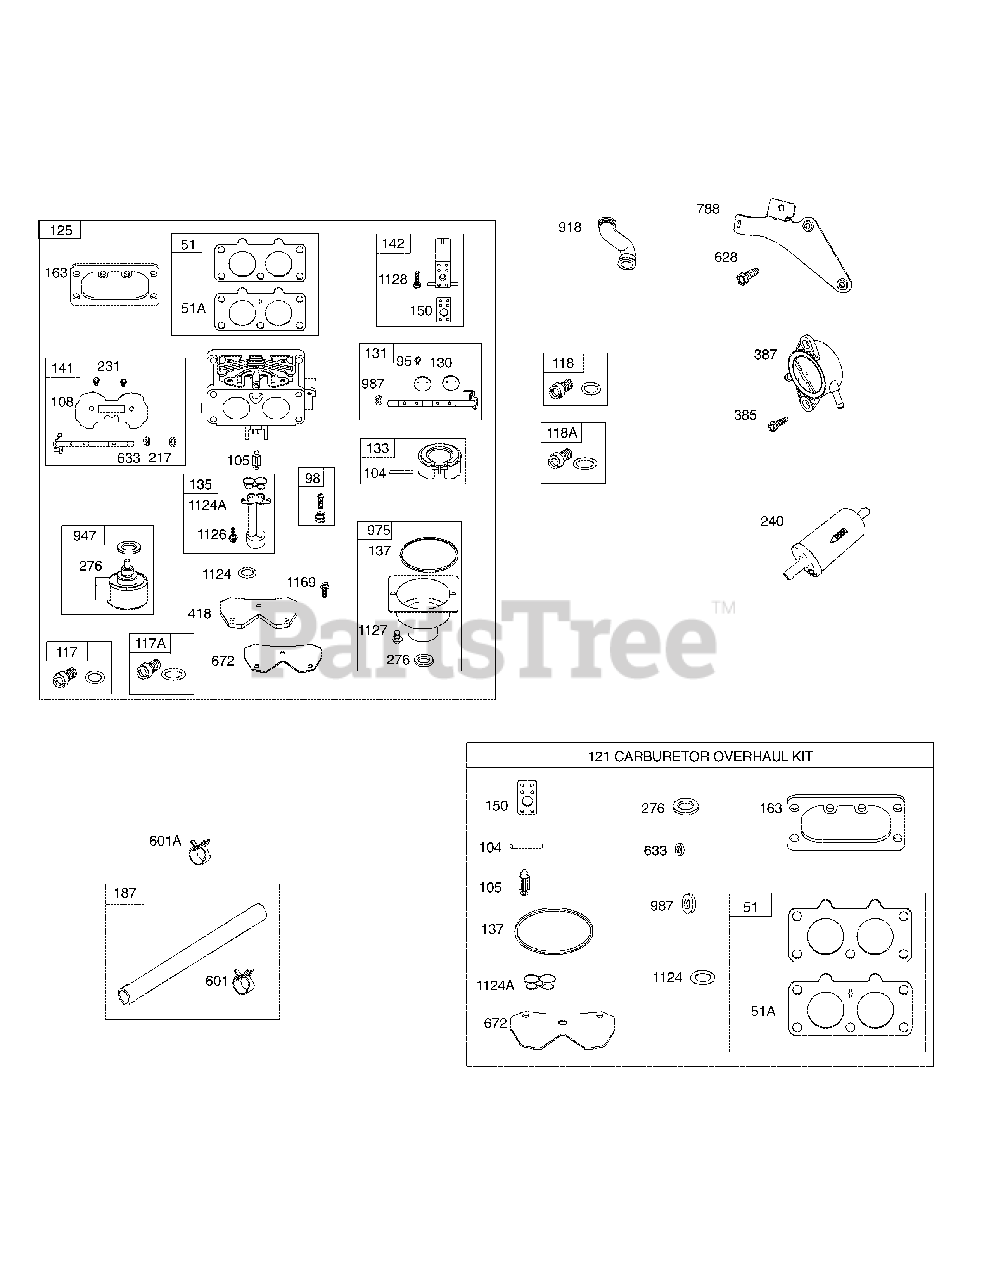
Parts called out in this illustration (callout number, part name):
1	Cylinder Assembly
2	Bushing/Seal Kit (Magneto Side)
3	Oil Seal (Magneto Side)
4	Engine Sump
5	Cylinder Head (Cylinder #1)
5A	Cylinder Head (Cylinder #2)
7	Cylinder Head Gasket
8	Breather Assembly
9	Breather Gasket
10	Screw (Breather Assembly)
11	Breather Tube
12	Crankcase Gasket
13	Screw (Cylinder Head)
15	Oil Drain Plug
16	Crankshaft
20	Oil Seal (PTO Side)
22	Screw (Crankcase Cover/Sump)
23	Flywheel
24	Flywheel Key
25	Piston Assembly (Standard)
25	Piston Assembly (.020" Oversize)
26	Ring Set (.020" Oversize)
26	Ring Set (Standard)
27	Piston Pin Lock
28	Piston Pin
29	Connecting Rod
32	Screw (Connecting Rod)
33	Exhaust Valve
34	Intake Valve
35	Valve Spring (Intake)
36	Valve Spring (Exhaust)
40	Valve Retainer
42	Valve Keeper
45	Valve Tappet
48	Short Block
50	Intake Manifold
51	Intake Gasket
51A	Intake Gasket
53	Stud (Carburetor)
54	Screw (Intake Manifold)
73	Rotating Screen
74	Screw (Rotating Screen)
75	Washer (Flywheel)
95	Screw (Throttle Valve)
98	Idle Speed Kit
104	Float Hinge Pin
105	Float Needle Valve
108	Choke Valve
117	Main Jet (Standard) (Left Jet)
117A	Main Jet (Standard) (Right Jet)
118	Main Jet (High Altitude) (Left Jet)
118A	Main Jet (High Altitude) (Right Jet)
121	Carburetor Overhaul Kit
125	Carburetor
130	Throttle Valve
131	Throttle Shaft Kit
133	Carburetor Float
135	Fuel Transfer Tube
137	Float Bowl Gasket
141	Choke Shaft Kit
142	Carburetor Nozzle
146	Timing Key
150	Nozzle Gasket
163	Air Cleaner Gasket
165	Nut (Ring Gear)
177	O-Ring Seal (Dipstick)
187	Fuel Line
188	Screw (Control Bracket)
192	Rocker Arm Adjuster
197	Screw (Back Plate)
209	Governor Spring (Dark Green/ Purple)
211	Governed Idle Spring (Orange)
212	Throttle Link
216	Choke Link
217	Choke Return Spring
219	Governor Gear
220	Washer (Governor Gear)
221	Governor Cup
222	Control Bracket
227	Governor Control Lever
231	Screw (Choke Valve)
239	Oil Pressure Switch
240	Fuel Filter
250	Breather Retainer
252	Oil Collector
265	Casing Clamp
267	Screw (Casing Clamp)
276	Sealing Washer (Fuel Solenoid)
278	Washer (Governor Control Lever)
287	Screw (Dipstick Tube)
304	Blower Housing
305	Screw (Blower Housing)
305A	Screw (Blower Housing to Intake Elbow)
306	Cylinder Shield (Cylinder #2)
307	Screw (Cylinder Shield) (1/4-20 x 2/3)
309	Starter Motor
310	Screw (Starter Motor)
332	Nut (Flywheel)
333	Magneto Armature
334	Screw (Magneto Armature)
337	Spark Plug
358	Engine Gasket Set
385	Screw (Fuel Pump)
387	Fuel Pump
404	Washer (Governor Crank)
415	Plug (Oil Pressure Switch)
418	Carburetor Plate
431	Intake Elbow
445	Air Cleaner Cartridge Filter
447	Screw (Air Guide Cover) (10-24 x 7/16)
447A	Screw (Air Guide Cover)
467	Air Cleaner Knob
474	Alternator
503	Starter Strap
505	Nut (Governor Control Lever)
510	Starter Drive
513	Drive Clutch
523	Dipstick
524	Dipstick Tube Seal
525	Dipstick Tube
526	Screw (Regulator)
544	Starter Armature
552	Governor Crank Bushing
552A	Governor Crank Bushing
562	Screw (Governor Control Lever)
573	Back Plate
579	Nut (Starter Cable)
601	Hose Clamp (Black)
601A	Hose Clamp (Green)
615	Governor Shaft Retainer
616	Governor Crank
617	O-Ring Seal (Intake Manifold) (Red)
628	Screw (Fuel Pump Bracket)
633	Choke Seal/Throttle Shaft
635	Spark Plug boot
654	Nut (Carburetor)
668	Spacer (Rotating Screen)
668A	Spacer (Rotating Screen)
672	Carburetor Plate Gasket
691	Governor Shaft Seal
695	Screw (Ring Gear)
697	Screw (Drive Cap)
718	Locating Pin
741	Timing Gear
742	E-Ring Retainer (Governor Crank)
750	Screw (Oil Pump Cover)
783	Pinion Gear
788	Fuel Pump Bracket
789	Wiring Harness
798	Screw (Rocker Arm)
803	Starter Housing
847	Dipstick/Tube Assembly
851	Spark Plug Terminal
865	Air Guide Cover (Cylinder #1)
865A	Air Guide Cover (Valley)
868	Valve Seal
877	Alternator Connector Wire
877A	Alternator Connector Wire
883	Exhaust Gasket
914	Screw (Rocker Cover)
918	Vacuum Hose
943	O-Ring Seal (Oil Pump Cover)
947	Fuel Solenoid
965	Oil Pump Cover
967	Pre-Cleaner Filter
968	Air Cleaner Cover
975	Float Bowl
987	Throttle Shaft Seal
1005	Flywheel Fan
1013	Oil Filter Nipple
1017	Oil Pump Screen
1022	Rocker Cover Gasket
1023	Rocker Cover (Cylinder #1)
1023A	Rocker Cover (Cylinder #2)
1026	Push Rod (Exhaust)
1026A	Push Rod (Intake)
1027	Oil Filter
1029	Rocker Arm
1036	Emissions Label
1051	Retaining Ring (Starter Drive)
1058	Operator's Manual
1059	Screw/Washer Kit (Alternator)
1070	Screw (Flywheel Fan)
1090	Brush Retainer
1095	Valve Gasket Set
1100	Rocker Arm Pivot
1119	Screw (Alternator)
1124	O-Ring Seal (Fuel Transfer Tube)
1124A	O-Ring Seal (Fuel Transfer Tube)
1126	Screw (Fuel Transfer Tube)
1127	Screw (Fuel Bowl)
1128	Screw (Carburetor Nozzle)
1169	Screw (Carburetor Plate)
